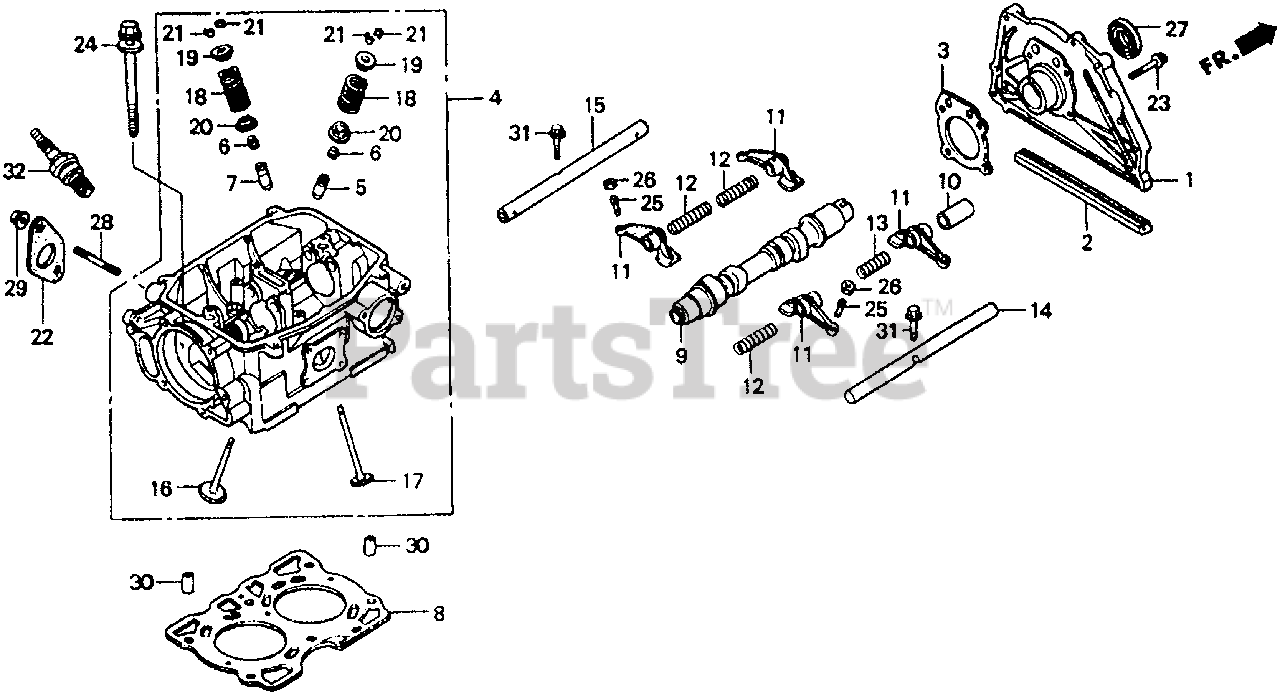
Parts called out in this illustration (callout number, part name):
1	COVER, RR. TIMING BELT
2	GASKET, RR. TIMING BELT COVER
3	GASKET, RR. TIMING BELT COVER
4	CYLINDER HEAD ASSY.
5	GUIDE, VALVE (OS)
6	SEAL, VALVE STEM (ARAI)
7	GUIDE, EX. VALVE
8	GASKET, CYLINDER HEAD
9	CAMSHAFT (20PS)
10	COLLAR, ROCKER ARM
11	ARM, ROCKER
12	SPRING, ROCKER ARM A
13	SPRING, ROCKER ARM B
14	SHAFT, IN. ROCKER
15	SHAFT, EX. ROCKER
16	VALVE, IN.
17	VALVE, EX.
18	SPRING, VALVE
19	RETAINER, VALVE SPRING
20	SEAT, VALVE SPRING
21	COTTER, VALVE
22	GASKET, EX. PIPE
23	BOLT, FLANGE (6X30)
24	BOLT-WASHER (10X115)
25	SCREW, TAPPET ADJ.
26	NUT, TAPPET ADJ.
27	OIL SEAL (28X40X8)
28	BOLT 2, STUD (8X22)
29	NUT, FLANGE (8MM)
30	PIN A, DOWEL (12X20)
31	BOLT, FLANGE (6X30)
32	SPARK PLUG (BPR5ES-11) (NGK)
32	SPARK PLUG (W16EPR-U11) (Honda Code 1870302). (DENSO)
